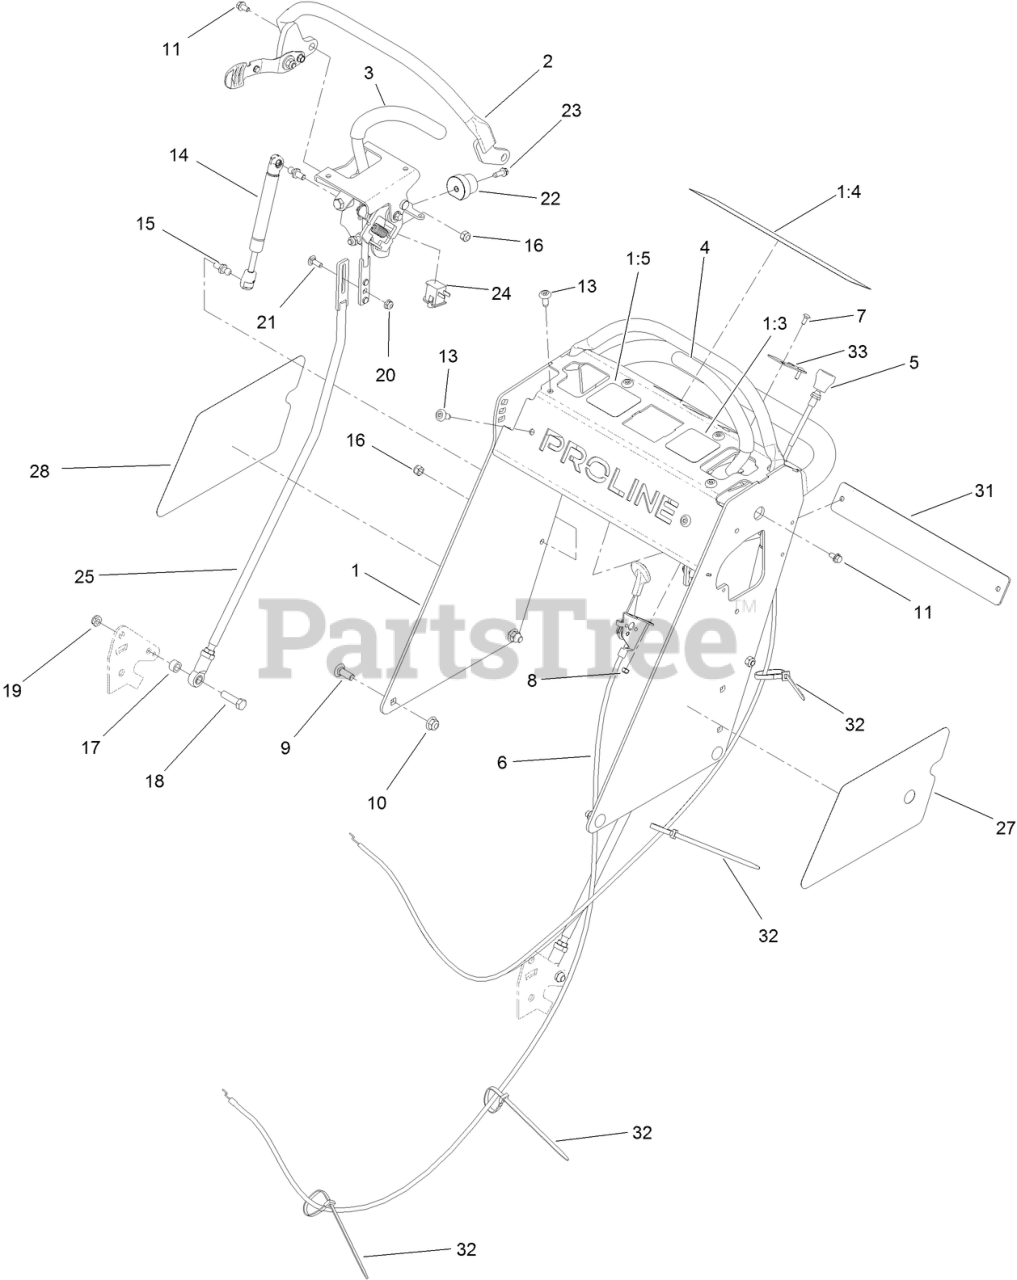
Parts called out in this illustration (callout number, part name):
1	TOWER ASM
1:3	DECAL-OPC CONTROL, LEFT
1:4	DECAL-WARNING, CONTROL
1:5	DECAL-OPC CONTROL, RIGHT
2	REFERENCE BAR ASSEMBLY
3	CONTROL HANDLE ASM, RH
4	CONTROL HANDLE ASM, LH
5	CABLE, CHOKE
6	CONTROL-THROTTLE
7	SCREW-CARR
8	NUT-LOCK, NI
9	SCREW-CARR
10	NUT-HF, NI
11	SCREW-HWH
14	DAMPER
15	STUD-BALL
16	NUT-LOCK, NI
17	SPACER
18	SCREW-HH
20	NUT-HF
21	BOLT-CARR
23	SCREW-HWHTF
24	SWITCH-BAIL
25	CONTROL ROD ASM
27	DECAL-PROLINE, LH
28	DECAL-PROLINE, RH
31	PLATE-COVER
32	TIE-PLASTIC
33	PLATE-SPEED LIMITER
